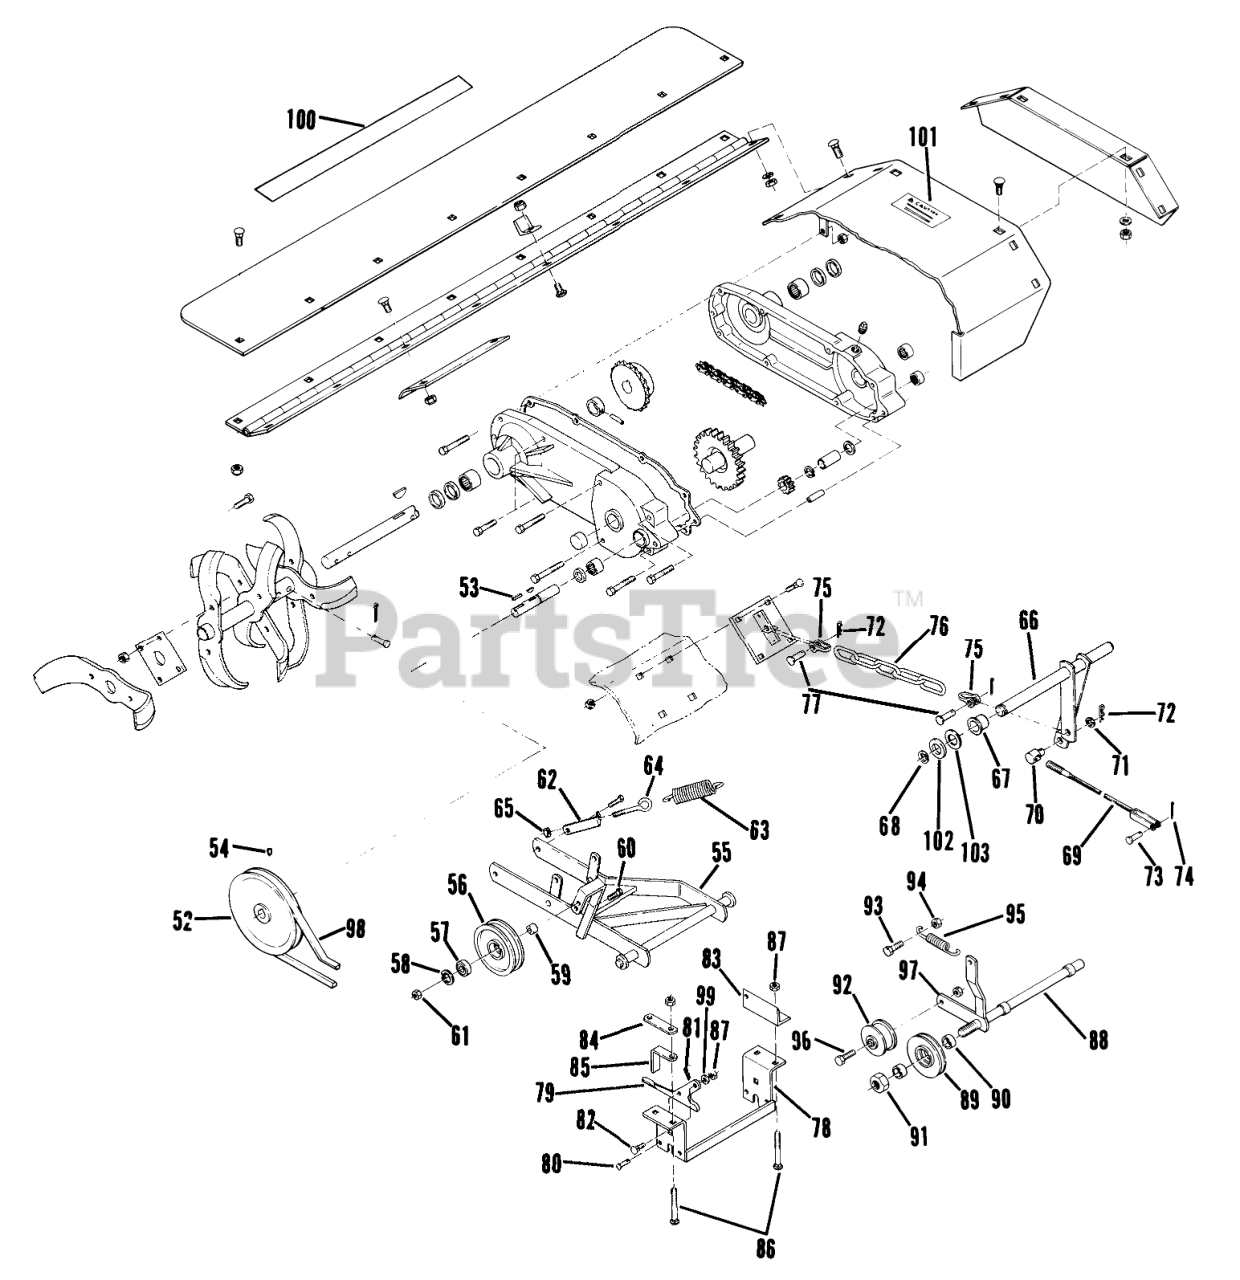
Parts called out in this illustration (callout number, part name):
51	WASHER 5/16 SAE
52	Pulley
53	KEY-STRAIGHT
54	Setscrew-Square Head
55	Hitch
56	Flat Idler
57	BEARING
58	INTERNAL SNAPRING
59	SPACER
60	HEX HD CAP SCREW
61	Nut
62	Bracket-Spring
63	SPRING
64	EYEBOLT
65	NUT
66	Lever Assy.
67	BUSHING
68	E-RING
69	ASSY-LIFT CABLE
70	TRUNNION-CLUTCH ROD
71	Washer
72	Hairpin
73	Pin
74	Cotter Pin
75	Clevis
76	CHAIN-LIFT
77	Clevis Pin
78	Bracket
79	PLATE-LATCHING
80	Pin
81	Hairpin
82	Bolt
83	Link
84	BRACKET-REAR LINK MOUNTING
85	SPACER-BRACKET
86	Bolt-Carriage
87	Nut
88	Front Idler
89	Pulley-V
90	Spacer
91	Nut
92	IDLER PULLEY
93	BOLT
93	Bolt
94	Nut
95	SPRING-BRAKE
97	Nut
98	V BELT
99	Washer
100	DECAL-WHEEL HORSE
101	Caution Decal
102	WASHER
